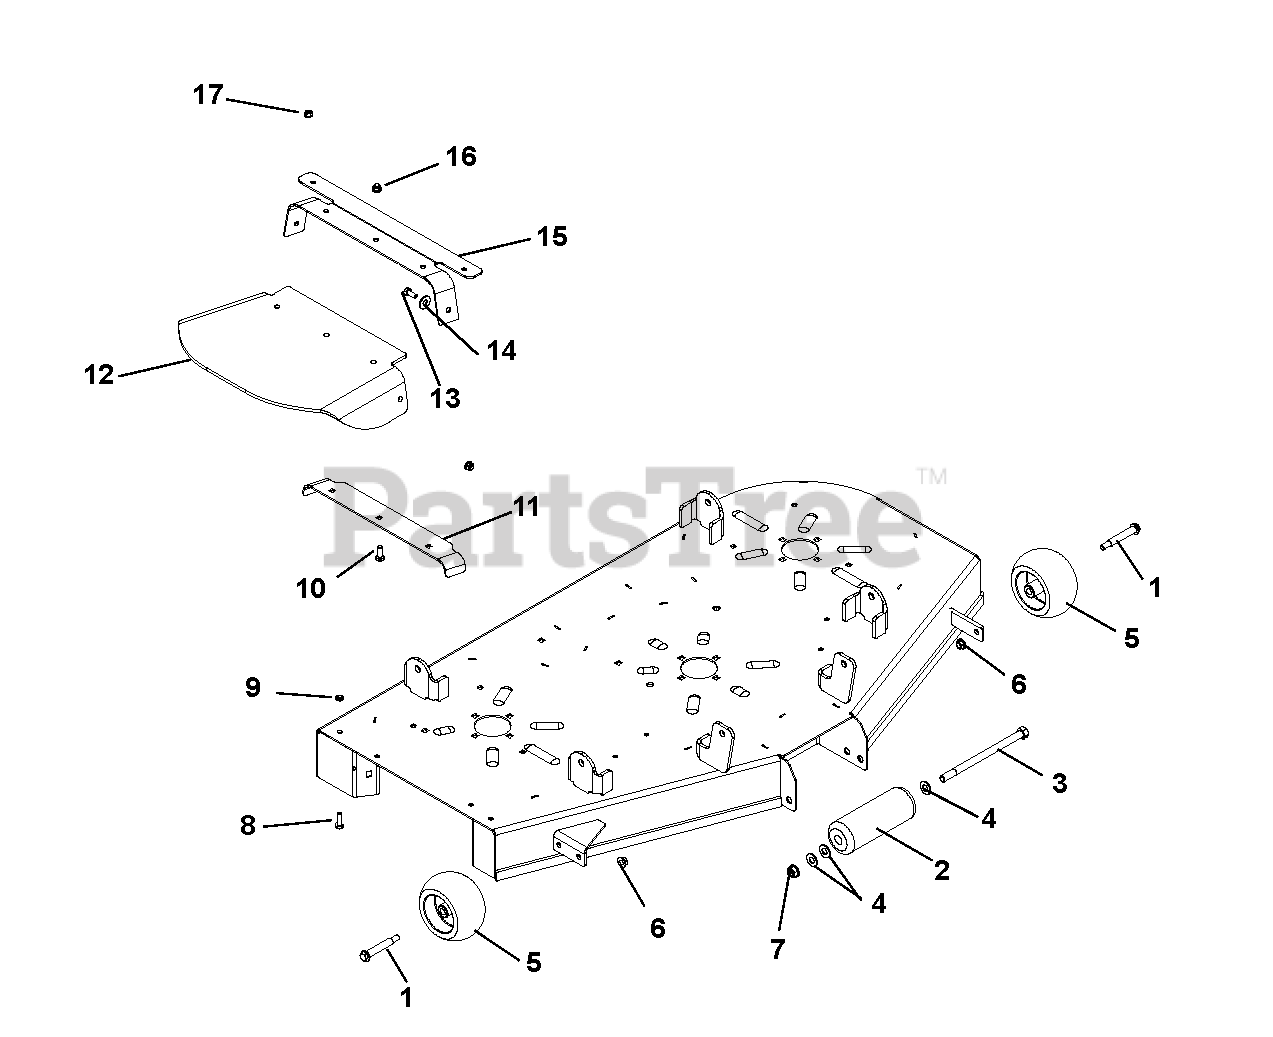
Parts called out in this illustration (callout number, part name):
1	Bolt, Shoulder .38-16 x 2.50 Hex Washer Head Grade 5
3	Bolt, Hex .50-13 x 8.00 Grade 5
4	Washer, Flat Nylon .52 x 1.00 x .08
5	Wheel 5 x 3
6	Nut, Locking Top Flange .38-16
7	Nut, Locking Nylon .50-13
8	Bolt, He x .31-18 x 1.00 Grade 5
9	Nut, Locking Center Jam .31-18
10	Bolt, Round Head Square Neck .31-18 x 1 Grade 5
11	Bracket, Chute Brace, Inner
12	Chute, Discharge, Rubber
13	Bolt, Hex .31-18 x .75 Grade 5
14	Washer, Flat Steel .438 x 1.00 x .083
15	Bracket, Discharge Chute
16	Nut, .31-18 Nyloc Flange
17	Nut, Nyloc Flange .31-18
